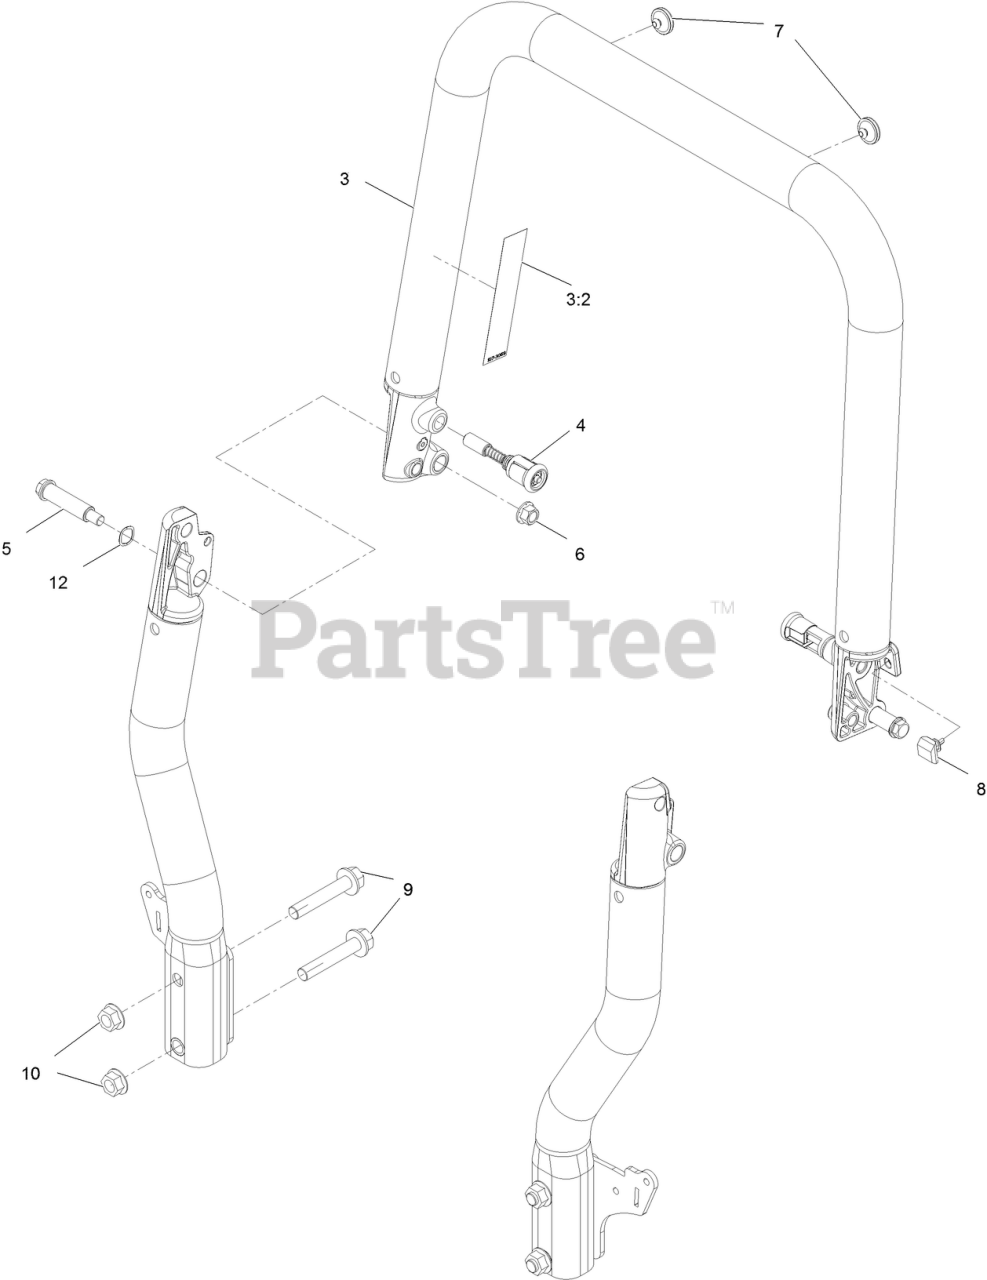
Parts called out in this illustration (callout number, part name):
3	TOP TUBE ASM
3:2	DECAL-WARNING
4	PIN-SPRING
5	BOLT-SHOULDER
6	Nut-Lock 1/2-13
7	BUMPER-ROPS
8	BUMPER-ROPS
9	SCREW-HHF
10	NUT-FLANGE
12	WASHER-WAVE
